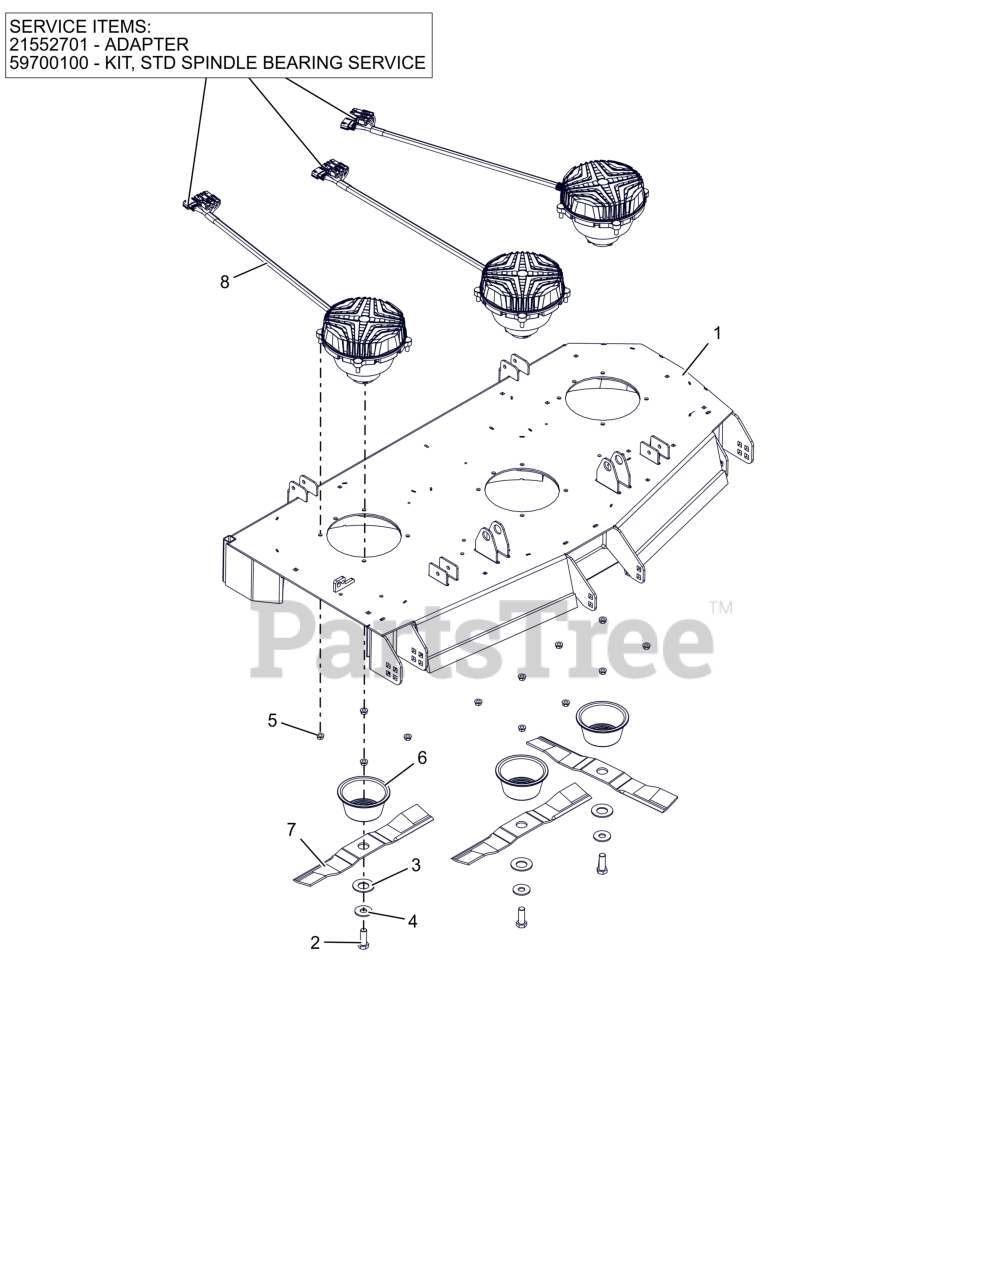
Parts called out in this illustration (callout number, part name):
1	WLDMT-52" PSEV SIDE DISCH DECK
2	BLT, HEX .62-18X1.75 G8 ZCC
3	WSHR, BLVL - .56X28.5X3 PHOS.COAT
4	WSHR, HRDN 0.687X1.75X0.134 HRD
5	NUT-LK-CTR-FLG .375-16 GF ZCC
6	GUARD, SPINDLE LOWER
7	BLADE, MOWER - 18.00" EFF CW
8	MOTOR, DECK - 48"/52" CW
8	ADAPTER
8	KIT, STD SPINDLE BEARING SERVICE
